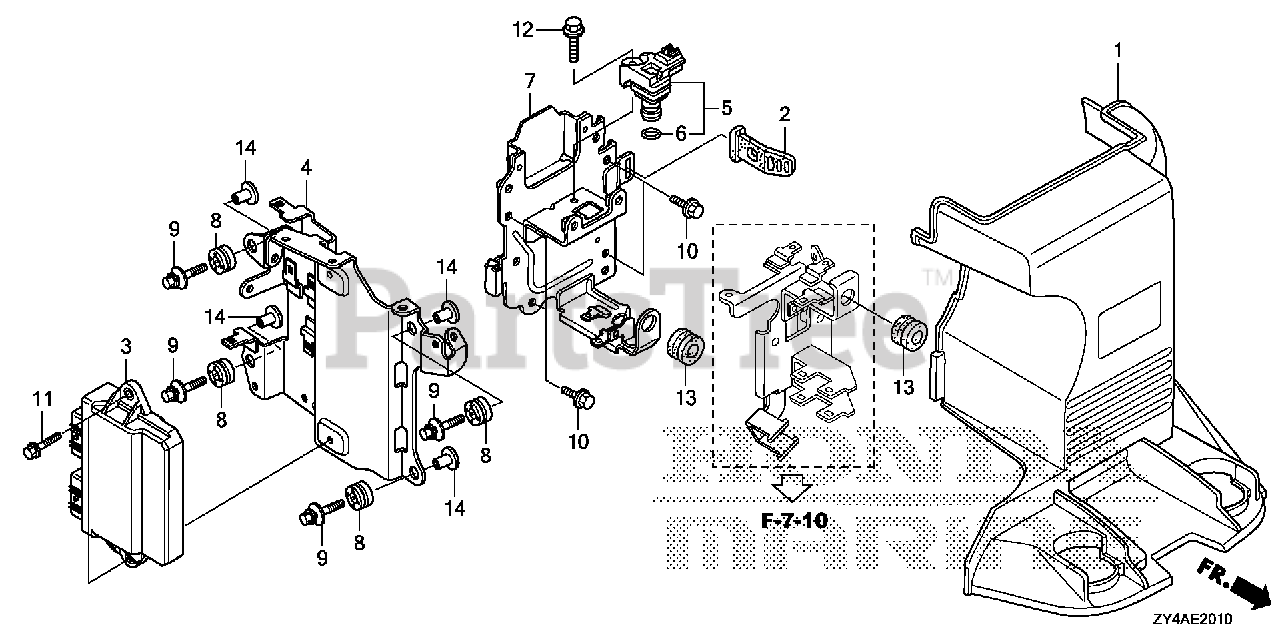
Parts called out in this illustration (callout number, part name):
1	COVER, ELECTRIC PARTS
2	BELT, COVER
3	CONTROL UNIT, ELECTRONIC
4	BRACKET, ECU
5	SENSOR ASSY., MAP
7	BRACKET, ELECTRIC PARTS
8	GROMMET, RELAY BRACKET
9	BOLT-WASHER (6X27) (CT200)
10	BOLT, FLANGE (6X14) (CT200)
11	BOLT, FLANGE (6X20)
12	BOLT-WASHER (5X18)
13	RUBBER, TANK CUSHION
14	COLLAR, MODULE IGNITION CONTROL CASE (CDI)
